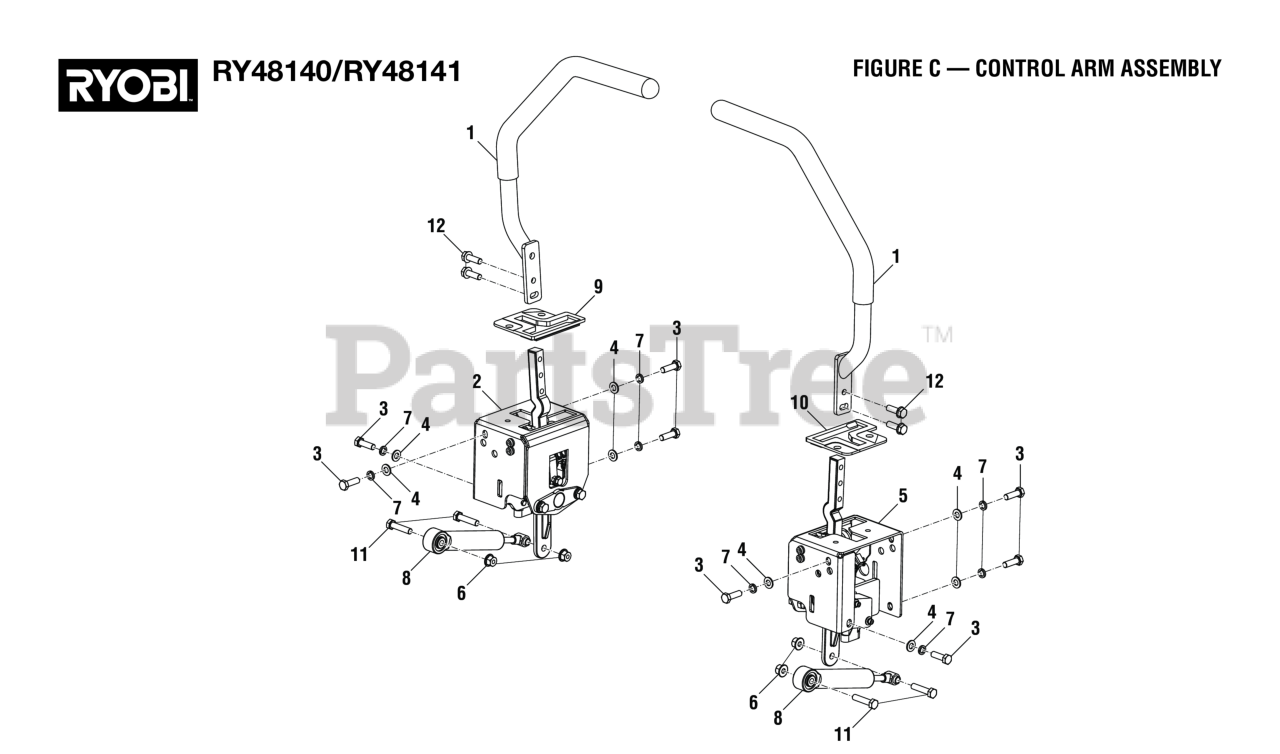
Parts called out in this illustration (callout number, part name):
1	Control Arm Handle
2	Control Arm Assembly, Left
3	Bolt (M8 x 25 mm, Hex Hd.)
4	Washer (OD16 x ID8.4 x 1.6t)
5	Control Arm Assembly, Right
6	Flange Nut (M8) (For Drive Motor Controller V)
7	Lock Washer (OD9.8 x ID8.5 x 5t)
8	Control Arm Damper
9	T Slot Insert, Left
10	T Slot Insert, Right
11	Bolt (M8 x 35 mm, Hex Hd.)
12	Bolt w/Washer (M8 x 25 mm, Hex Hd.)
